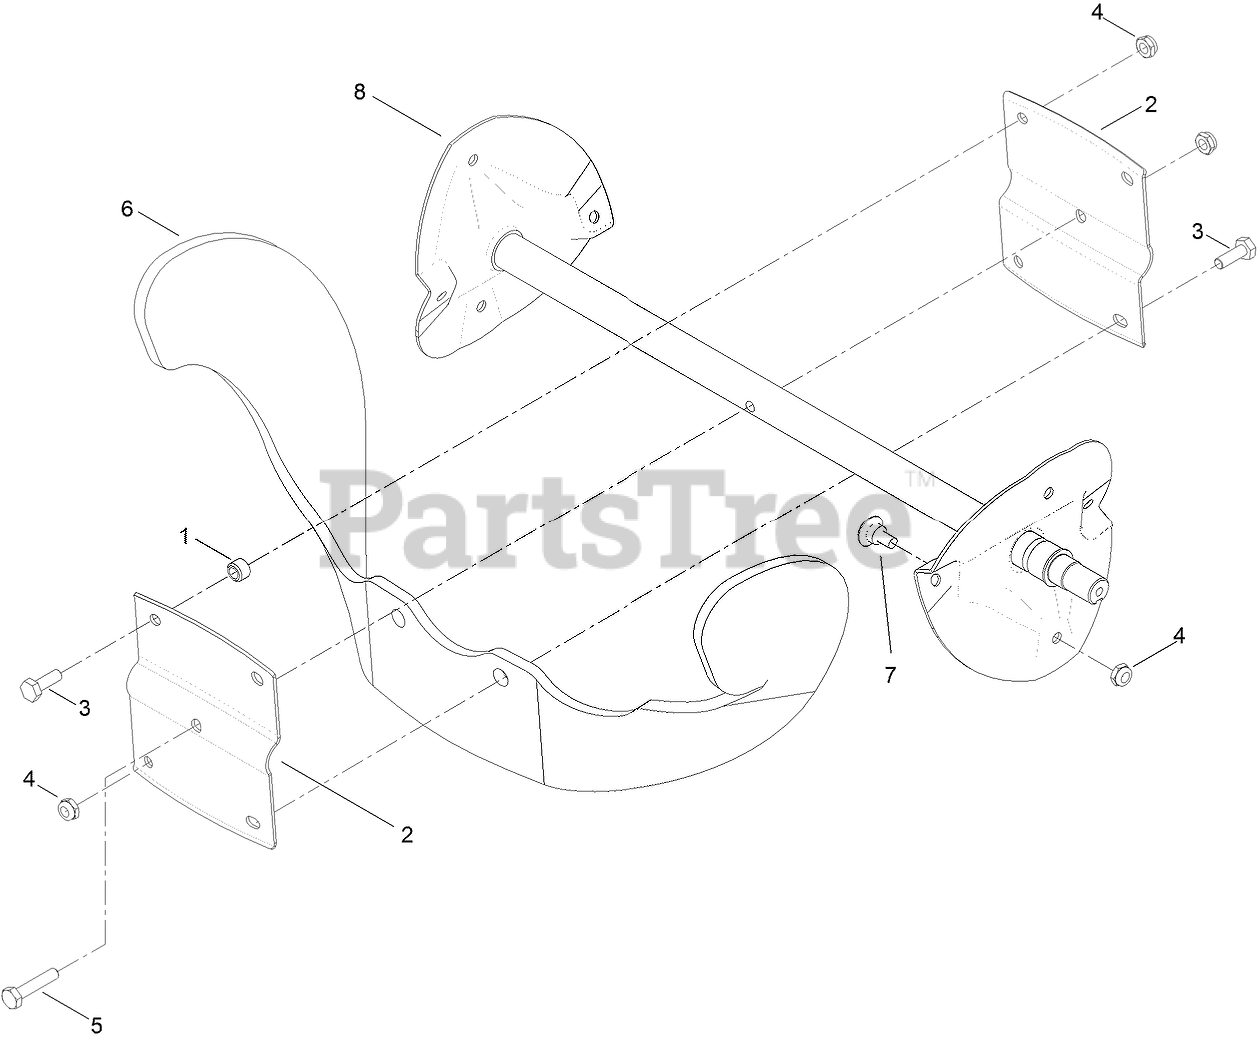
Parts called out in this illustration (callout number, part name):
1	SPACER-BLADE, ROTOR
2	HALF-ROTOR
3	SCREW-HH
4	NUT-LOCK, NI
5	SCREW-HH
6	BLADE-ROTOR
8	ROTOR
